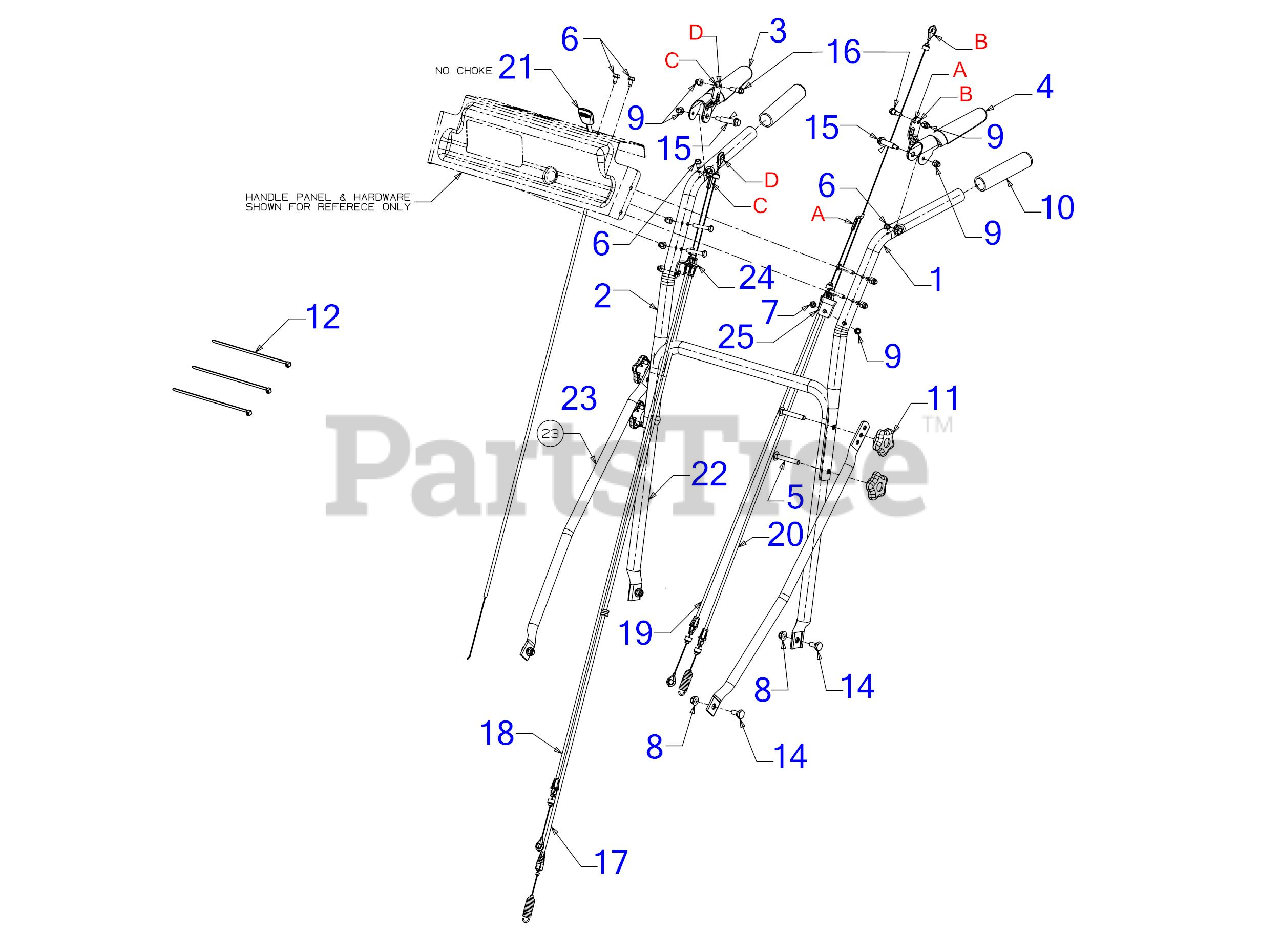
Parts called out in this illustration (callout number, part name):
1	UPPER HANDLE ASSEMBLY (LH)
2	UPPER HANDLE ASSEMBLY (RH)
3	LEVER ASSEMBLY (RH)
4	LEVER ASSEMBLY (LH)
5	SCRE W5/16-18 x 2.25 GR5
6	SCREW 1/4-20 X.500
7	SCREW 1/4-20 x 1.50 GR.5
8	FLANGE LOCK NUT 5/16-18
9	HEX ACORN NUT
11	STAR KNOB 5/16-18
12	7" CABLE TIE
14	SHOULDER SCREW .437
15	SHOULDER BOLT .375X1.285:1/4-20
16	SHOULDER SCREW .342X.335X1/4-20
17	BLADE CONTROL CABLE
18	TRANSMISSION BRAKE CABLE (RH)
19	TRANSMISSION BRAKE CABLE (LH)
20	WHEEL CLUTCH CABLE
21	THROTTLE CONTROL CABLE
23	HANDLE ADJUSTMENT BRACE
24	CABLE BRACKET MOUNTING (RH)
25	CABLE BRACKET MOUNTING (LH)
